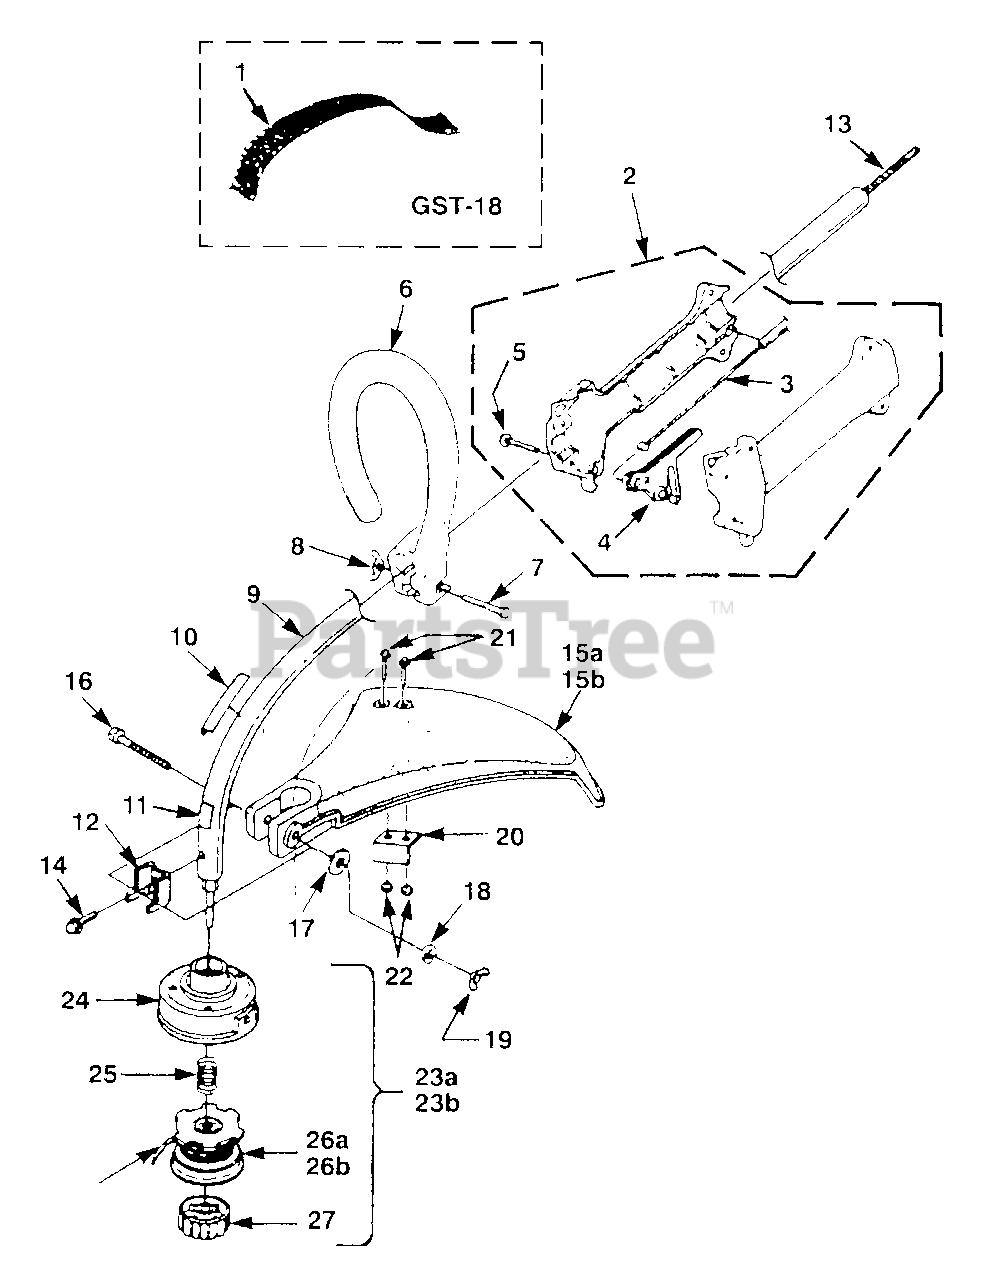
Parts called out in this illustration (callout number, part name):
1	HARNESS w/Connector
2	HANDLE GRIP ASSEMBLY
3	CABLE - Throttle
4	TRIGGER
5	SCREW - Thread Forming (#8 X 3/4")
6	FRONT HANDLE KIT
7	SCREW - Cap Hex Hd (1/4-20 X 2")
8	NUT - Wing (1/4-20)
9	HOUSING - Drive Shaft
10	DECAL - Starting Instructions
11	DECAL - Warning
12	CLAMP
13	SHAFT - Flexible
14	SCREW - Sems Hex Hd (#10 X 1/2")
16	SCREW - Cap Hex Hd (10-24 X 2")
17	WASHER - Flat (1/4")
18	WASHER - Lock (1/4")
19	NUT - Wing (10-24)
20	BLADE - Cut-Off
21	SCREW - Mech Hex Hd (10-24 X 7/8")
22	NUT - Hex (10-24)
24	HOUSING & EYELET
25	SPRING - Compression
27	RETAINER - Spool
